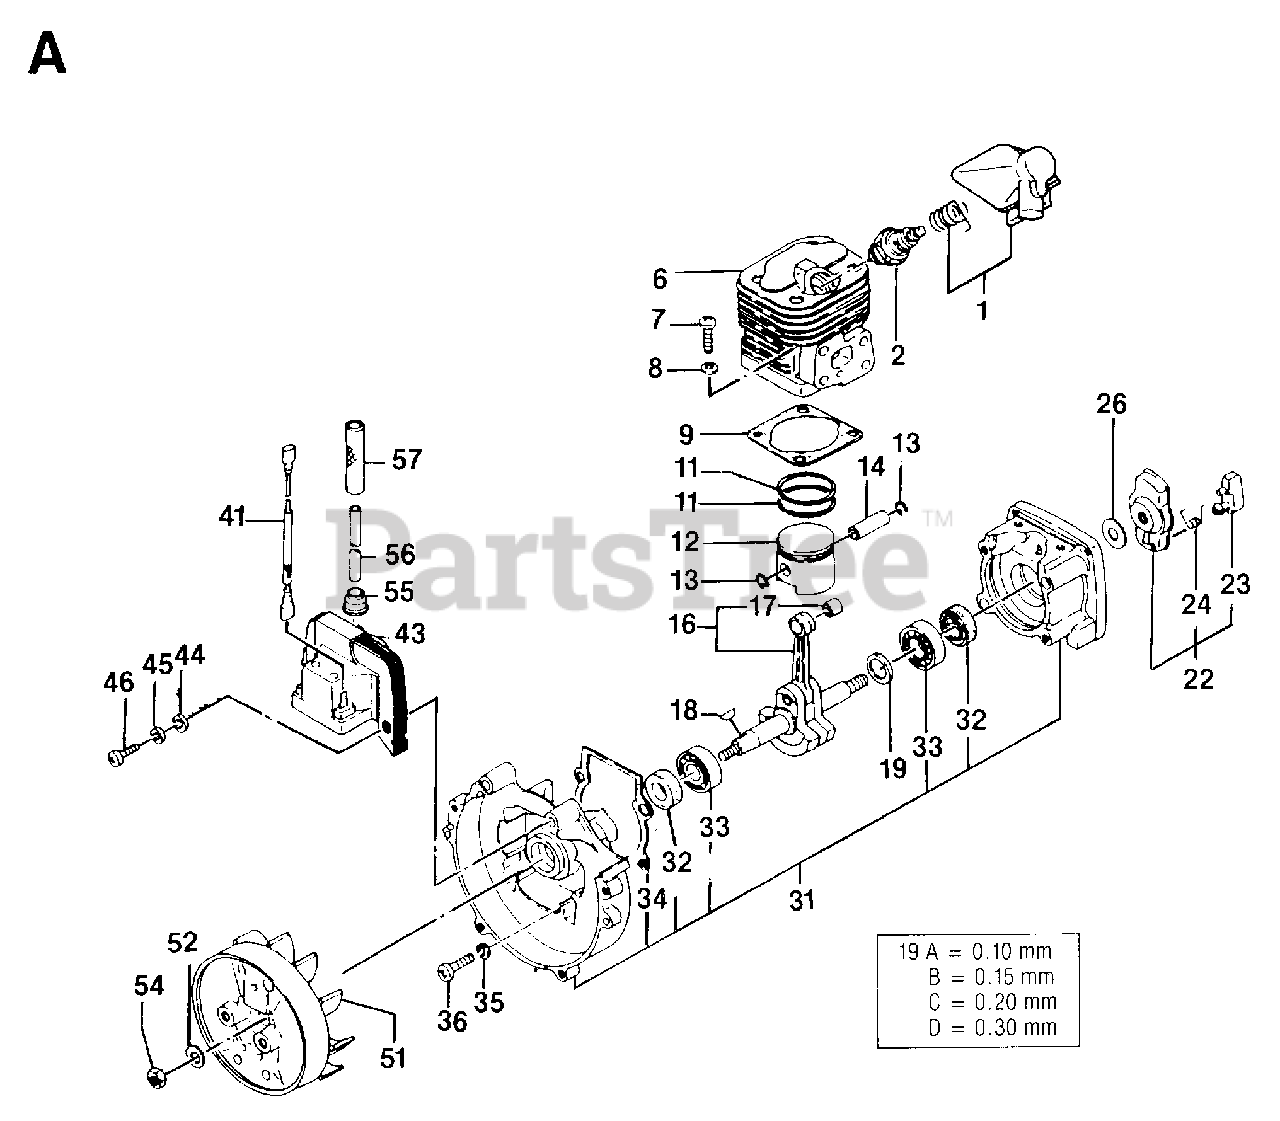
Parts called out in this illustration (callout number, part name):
2	SPARK PLUG CJ8 NLA
8	SPRING WASHER
35	SPRING WASHER
36	SCREW MC6S 5X25
44	WASHER
45	SPRING WASHER
46	SCREW MC6S 5X20
